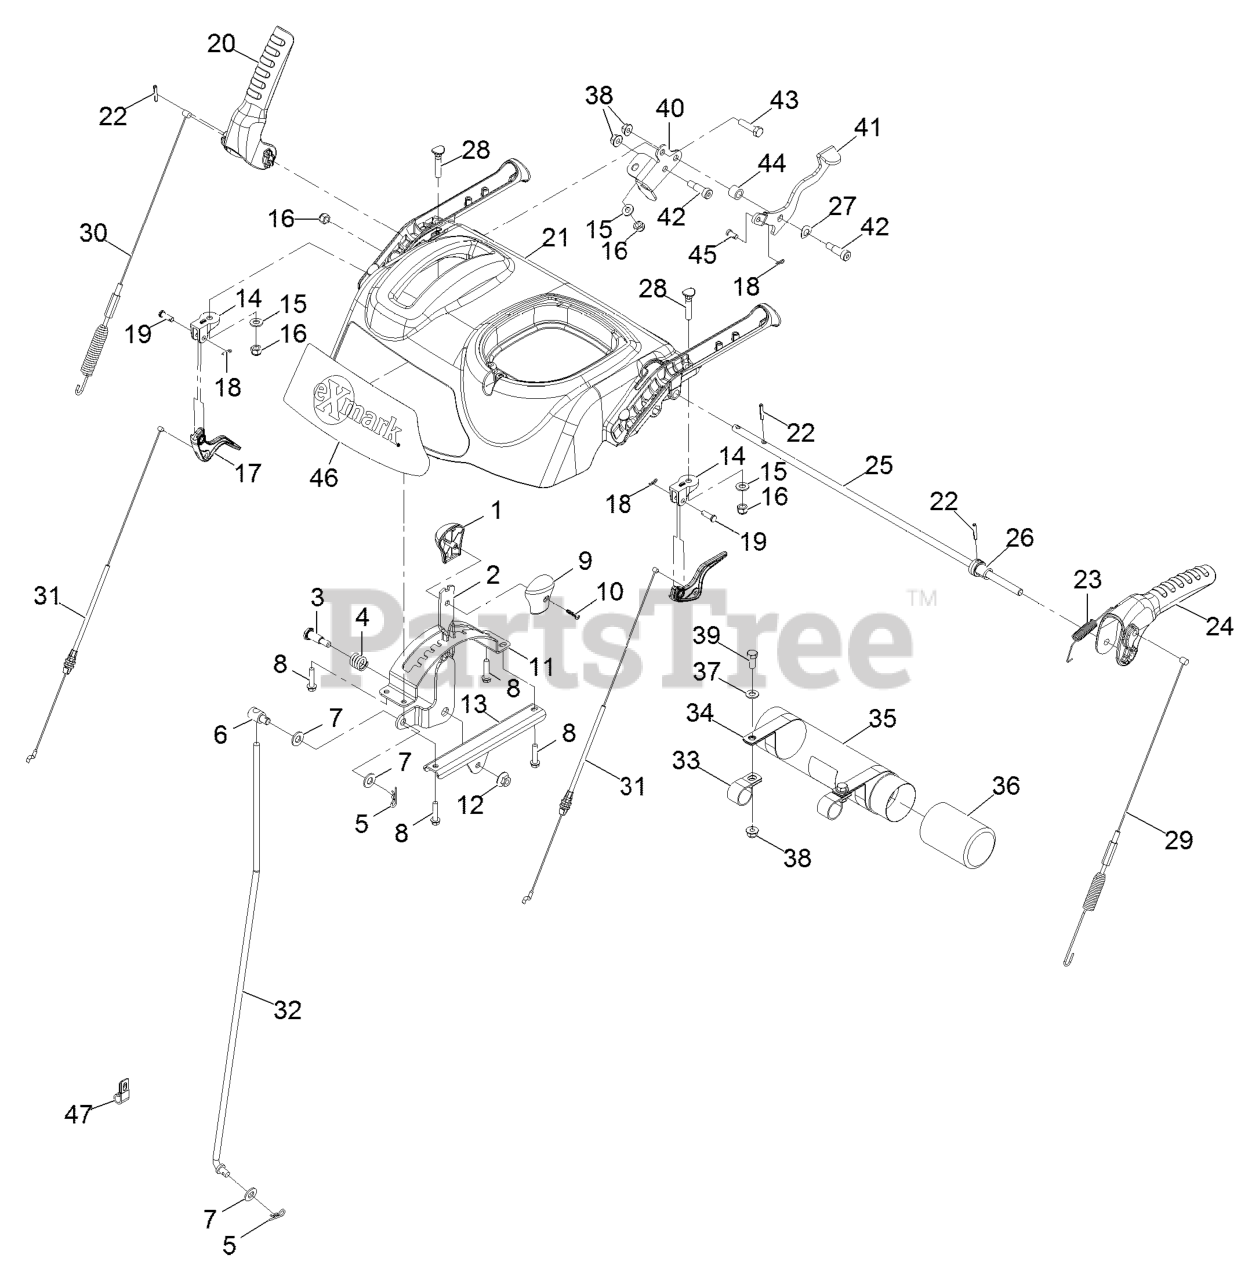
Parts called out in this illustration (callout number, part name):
1	KNOB-SHIFT, RH
2	SELECTOR-SPEED
3	SCREW-SHOULDER
6	TRUNNION-ROD
7	WASHER-FLAT
8	SCREW-PLASTITE
9	KNOB-SHIFT, LH
10	SCREW-PPH
11	GUIDE-SELECTOR, SPEED
13	MOUNT-SELECTOR, SPEED
14	MOUNT-LEVER, CLUTCH
15	WASHER-FLAT
16	NUT-LOCK, NI
17	LEVER-CLUTCH
18	PIN-HAIR
19	PIN-CLEVIS
20	LEVER-AUGER
21	PANEL, CONTROL W/DECAL CE
22	PIN-SPRING
23	SPRING-TENSION
24	LEVER-TRACTION
25	ROD-LOCKOUT
26	CAM-LOCKOUT
27	WASHER-SPRING
28	SCREW-HANDLE
29	CABLE-TRACTION
30	CABLE-AUGER
31	CABLE-CLUTCH
33	CLAMP-R
34	CLAMP-R
35	TUBE-MANUAL
36	CAP-HOUSING
37	WASHER-PLAIN
38	NUT-HF, NI
39	SCREW-HH
40	BRACKET-LEVER, BROOM ANGL
41	LEVER-THUMB, BROOM ANGLE
42	SCREW-SHOULDER, HSH
43	SCREW-HH
44	TUBE-SPACER
45	PIN-CLEVIS
46	DECAL-EXMARK LOGO
47	CLIP-LOOM
